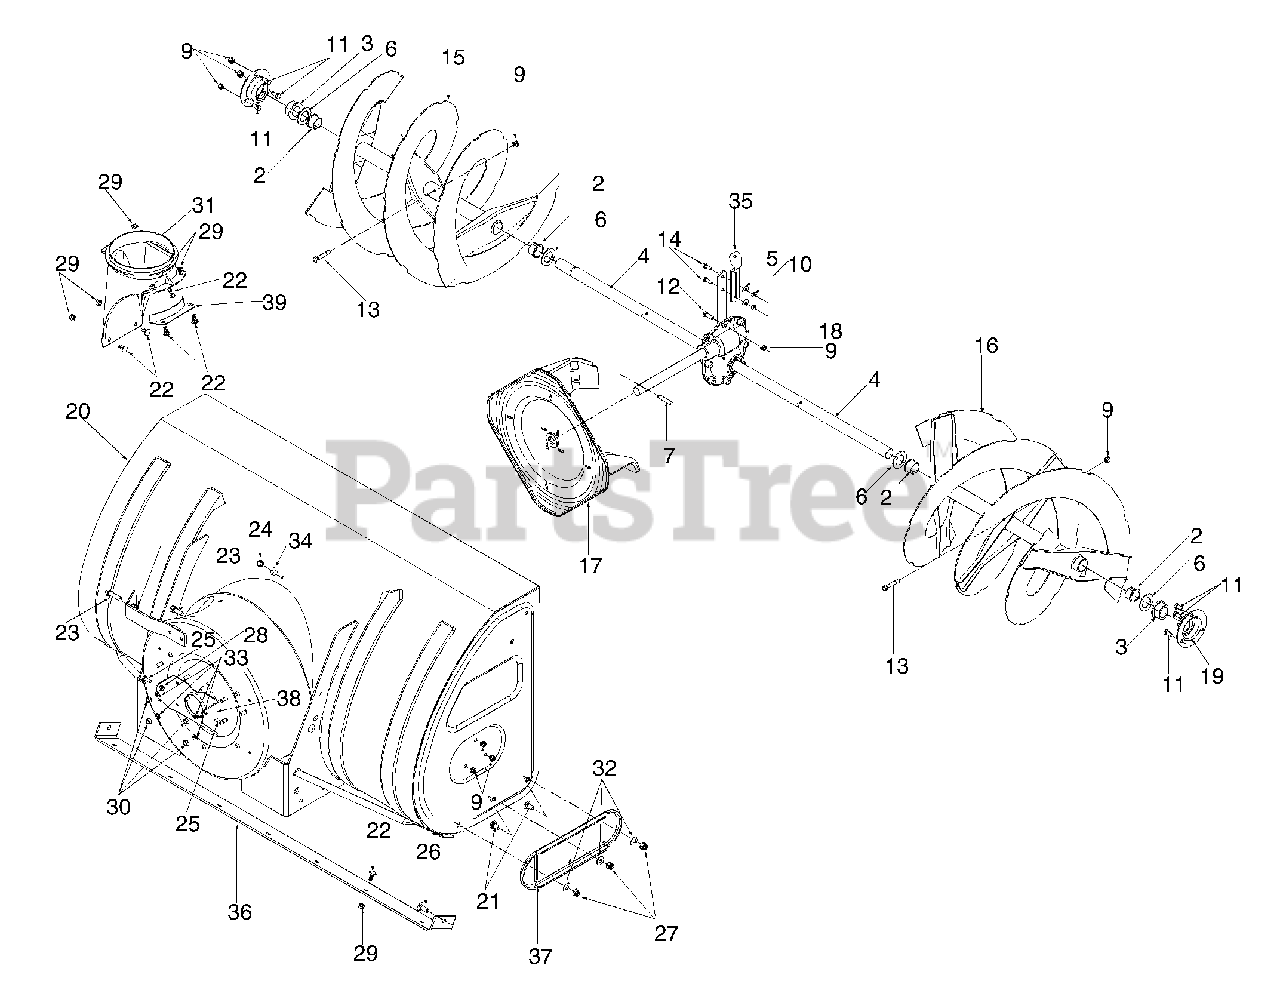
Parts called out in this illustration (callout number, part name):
1	PLATE-SUPPORT
2	BUSHING
3	BEARING-FLANGE
4	AXLE-SPIRAL
5	WASHER-SPRING BELL
6	WASHER-FL
7	PIN-SPRING SPIR 5/
9	NUT-HEX INS
10	NUT-HEX 1/4-28
11	SCREW-HEX 5/16-18X
12	SCREW-HEX 5/16 X 3
13	HEX BOLT 5/16-18 X 1.75
14	SCREW-HEX 1/4-28 X
18	AUGER GEARBOX ASSEMBLY
19	HOUSING BEARING
22	CARRIAGE BOLT 5/16-18 X .75
23	SCREW-HEX 3/8-16 X
24	SCREW-HEX HD TAP
25	SCREW-HEX 1/4-20X.
26	CARRIAGE BOLT 3/8-16 X 1.00
27	NUT-HEX INS L-3/8-
28	NUT-NYLON LK 1/4X2
29	NUT-HEX INS
30	NUT-HEX 5/16-18
31	CHUTE ADAPTER
32	WASHER-BELL .400 I
33	WASHER-LOCK 5/16
34	WASHER-BELL .337 X
35	PLATE-SUPPORT-GEAR
36	PLATE-SHAVE 45"
38	BRACKET-BEARING MOUNTING
39	BRACKET CHUTE
